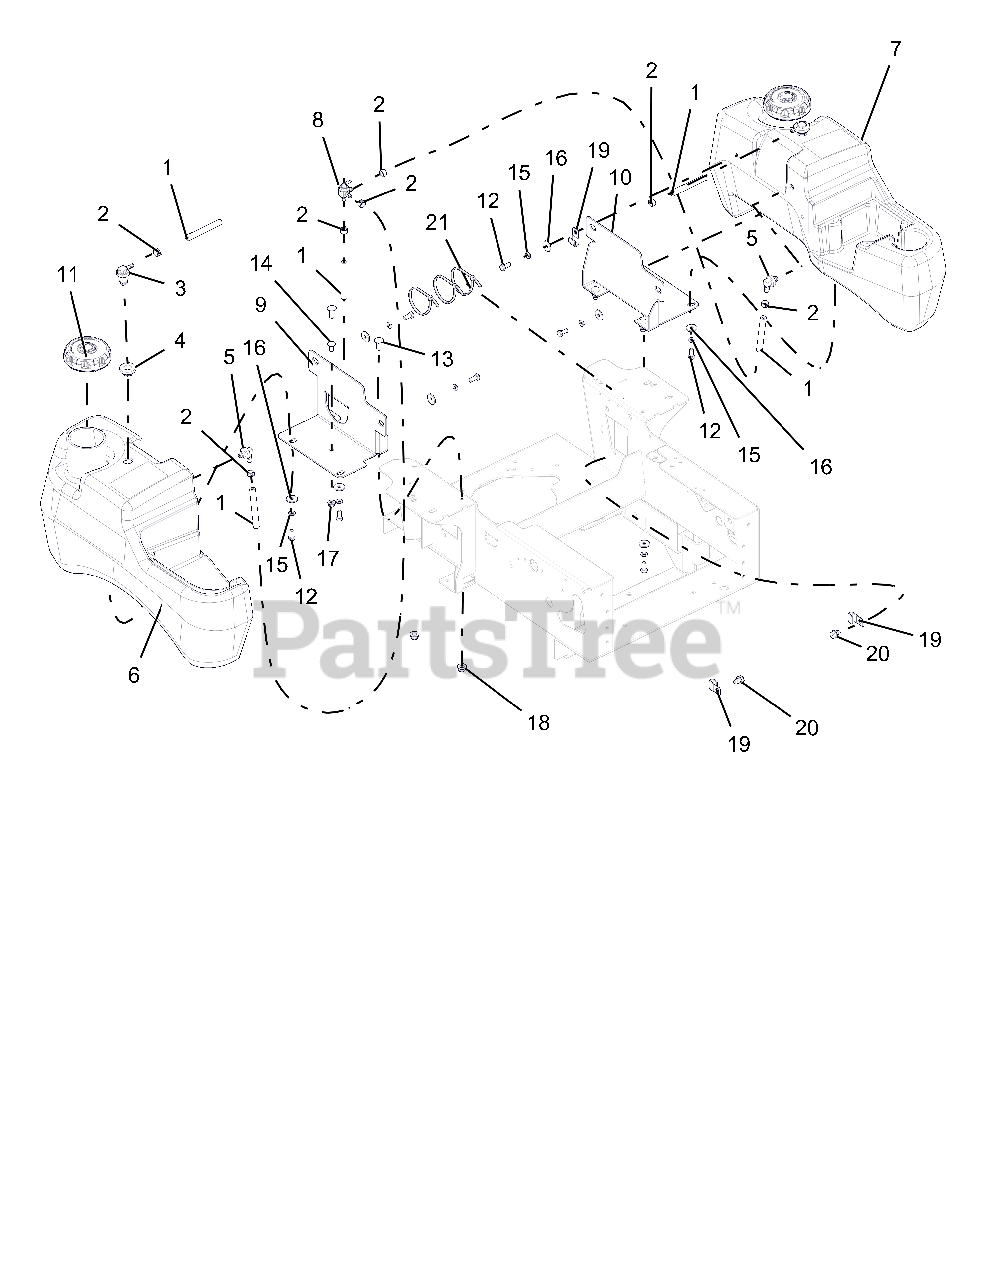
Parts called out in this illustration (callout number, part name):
1	.25 LOW-PERM GAS HOSE
2	CLAMP, FUEL LINE
3	VALVE, COMBINATION
4	GROMMET, REMOTE VENT NITRILE
5	ASS'Y, SMALL/ MED TANK FUEL PICK-UP
6	TANK, GAS - RH MEDIUM GRAVELY
7	TANK, GAS - LH MEDIUM GRAVELY
8	VALVE, FUEL
9	BRKT, RH MEDIUM FUEL TANK MTG
10	BRKT, RH MEDIUM FUEL TANK MTG
11	CAP, NON NONVENT AUTOLOCK
12	BLT-HEX .31-18X.75 GR5 YWZC
13	BLT-RDHDSHSQNK.38-16X1.0 G5YZ
14	BLT-RDHDSQNK .31-18X.75 G5 YWZC
15	WSHR-LK .31X.078 REG YWZC
16	WSHR-FL-STL .328X1.00X.094 YWZC
17	NUT-LK-NYL-FLG .31-18 YWZC
18	NUT-LK-NYL-FLG .38-16 YWZC
19	CLAMP, J
20	SCR-TAP .38-16X.50 HWH TR YWZ
21	CABLE, TIE 5.50 LG
